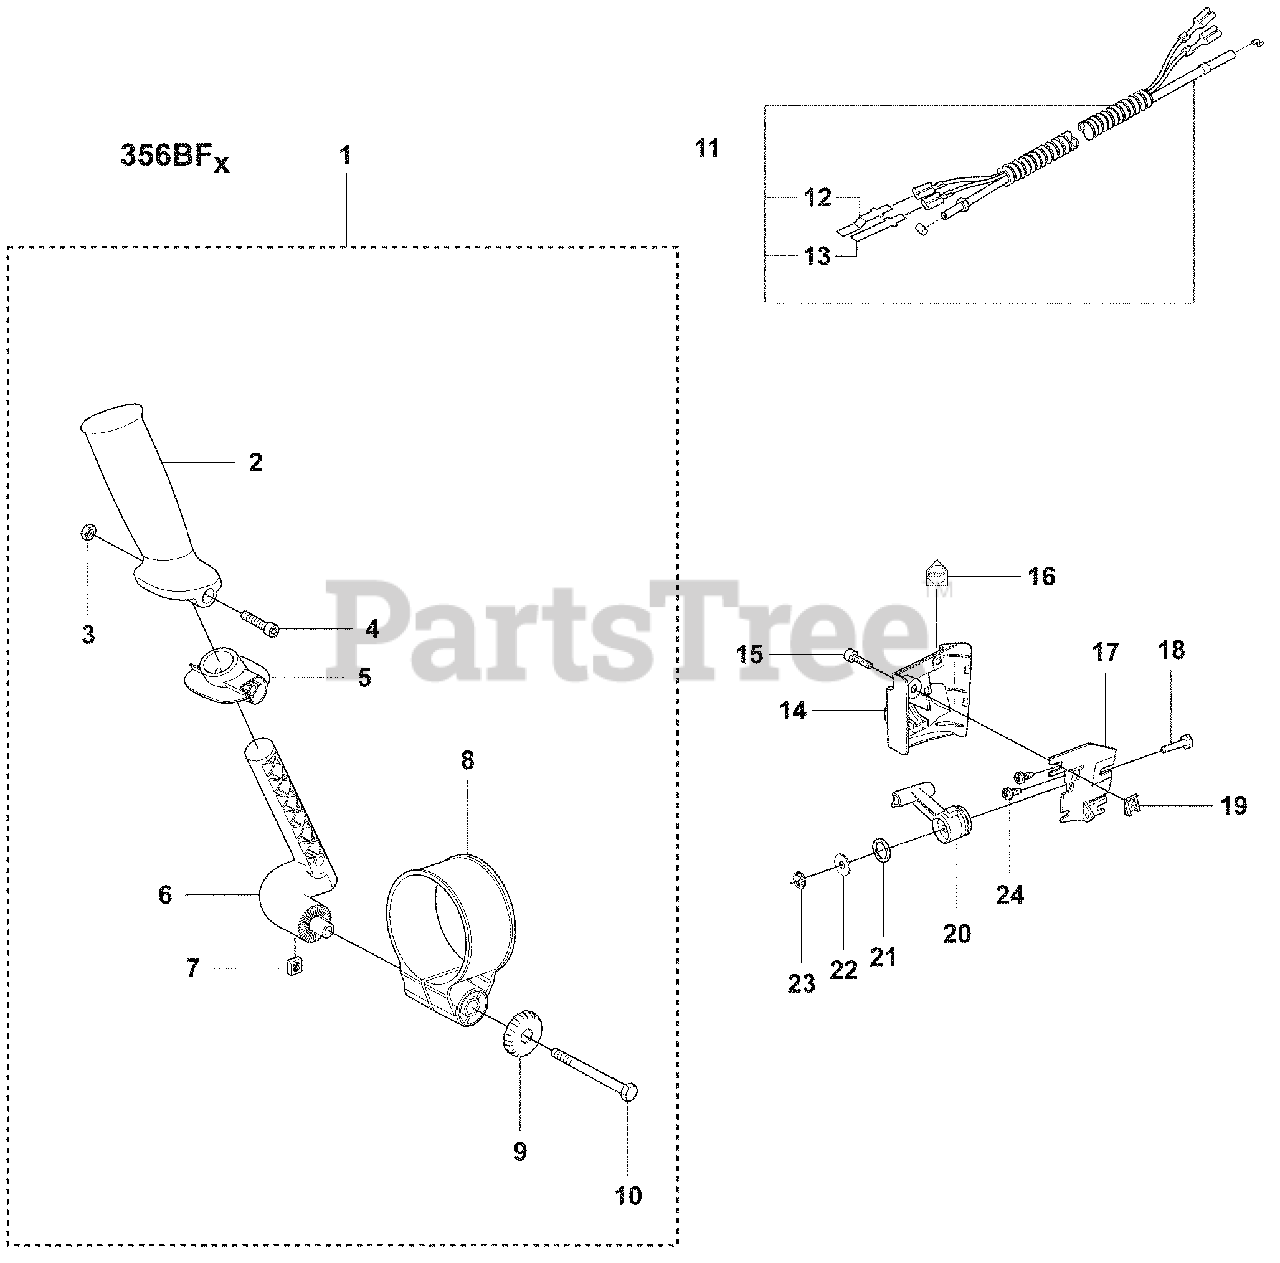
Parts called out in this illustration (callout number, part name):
3	Hex Nut, M5 X .80 DIN
4	Screw
6	Holder
7	Square Nut
9	Air Filter Cover Knob
11	Cable Assembly
21	Spring, Rubber
22	Washer, M5 Large
